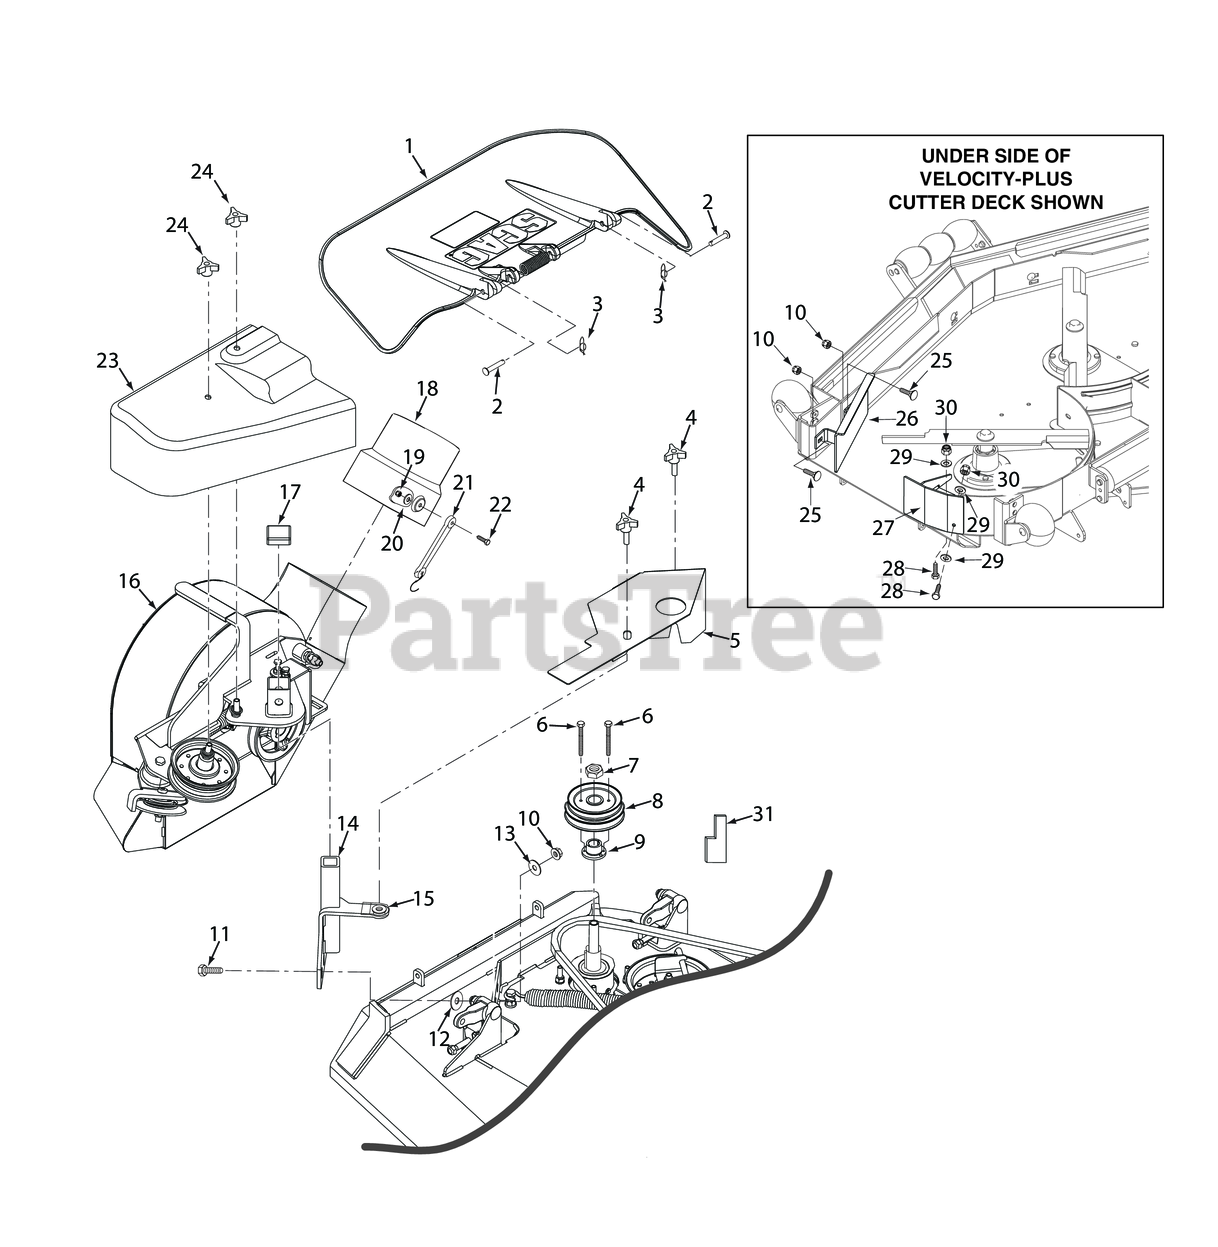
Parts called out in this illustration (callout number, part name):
1	Discharge Chute Assembly - 48V
1	Discharge Chute Assembly - 52V
1	Discharge Chute Advantage - Large
2	Clevis Pin, 5/16 x 1-1/2"
3	Pin, Rue Cotter 5/16 Dia.
4	Knob, w/stud 3/8-16 x 1-1/4"
5	Belt Cover, 48GC-VRII
5	Belt Cover, 52GC-VRII
5	Belt Cover, 61GC-VRII
6	Bolt, 1/4-20 x 2½" Full Thread
7	Hex Locknut, Elastic Stop, 3/8-16
8	Pulley, Double Groove
8	Pulley, Double Groove (52)
8	Pulley, Double Groove (61)
9	Hub, Tapered 1-1/8" Bore
10	HEX NUT, ELASTIC STOP LOCK, 3/8-16
11	Bolt, Hex Head 3/8-16 x 1-1/4", Kawasaki FX / FS
12	Flatwasher, 3/8" Special (.391 x .938 x .105)
13	Lockwasher, 3/8" Spring, Kawasaki FX / FS
14	Mounting Post Assembly, Blower - 48GC-VRII (INCL.15)
14	Mounting Post Assembly, Blower - 52GC-VRII (INCL.15)
14	Mounting Post Assembly, Blower - 61GC-VRII (INCL.15)
15	U-Nut, 3/8-16 (short)
16	Blower Assembly, 48/52GC-VRII
16	Blower Assembly, 61GC-VRII
17	Cap, Square Vinyl
18	Adapter, Blower GC-STC,
19	SERR. FLG. HEX HEAD CAPSCREW, 5/16-18 X 3/4
20	Flatwasher, 1/4" (.312 x .750 x .065")
21	Rubber Strap 7-3/4"
22	HEX, NUT, ELASTIC STOP LOCK, 1/4-20
23	Belt Cover, 48GC-VRII
23	Belt Cover, 52GC-VRII
23	Belt Cover, 61GC-VRII
24	Wing Nut, 3/8-16 (Small) Top side
25	Carriage Bolt, 3/8-16 x 1.0"
26	Baffle Weldment, 52V Deck
26	Baffle Weldment - 61" Deck
27	Baffle, Turbo 48" Deck
27	Baffle, Turbo 52" Deck
27	Baffle, Turbo - 61" Deck
28	Bolt, Heax Head 5/16-18 x 1" (48V / 52V)
29	Flatwasher, 5/16-.375 x .875 x .083 (35BV & 37BV-EFI)
30	HEX NUT, ELASTIC STOP LOCK, 5/16-18
31	Pulley Height Tool
